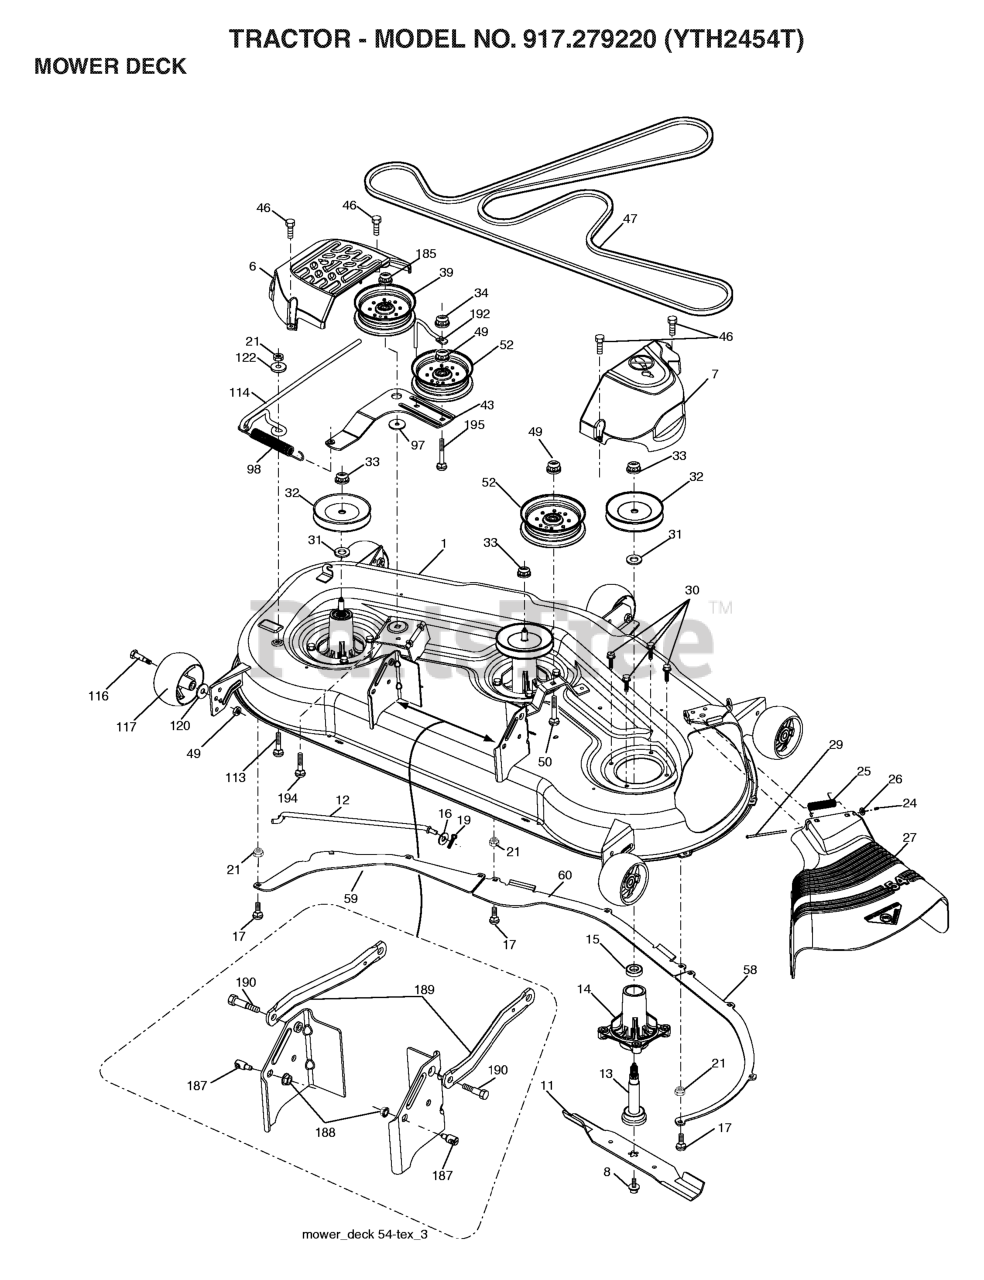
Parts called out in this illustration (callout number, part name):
1	DECK.WELDMENT.54"MS418
6	COVER.MANDREL.LH.54"20
7	COVER.MANDREL.RH.54.20
8	BOLT 7/16 ASM BLADE
11	BLADE.BAGGING.54"
12	ROD.ANTI.SWAY.48/54"TE
13	SHAFT ASM MANDREL
14	RP.HOUSING.MANDREL.4PT.
16	WASHER
17	BOLT
19	PIN.COTTER.5/16.BOW TI
21	LOCKNUT
24	CAP-SLEEVE LT
25	SPRING, TORSION
26	NUT PUSH M
27	DEFLECTOR
29	ROD.HINGE
30	SCREW, WASHER HEAD
31	WASHER.SPACER.MANDREL
32	MANDREL.PULLEY.38.BRIGHT.ZINC
33	NUT.FLANGE.LOCK.TOP
39	PULLEY.IDLER.MWR.STATI.LH
46	SCREW.1/4-20X5/8
47	RP.BELT.DRIVE.54."2006
49	NUT LOCK FLG 3/8-16 UNC
52	PULLEY.IDLER.2006
58	BAFFLE.RIGHT.54"
59	BAFFLE.LEFT.54"
60	BAFFLE CENTER 54" MOWER
98	SPRING, DECK DRIVE
114	ROD TENSION RELIEF
116	BOLT.SHOULDER.3/8-16X3-5/8.
117	RP WHEEL. GUAGE RALLY
120	WASHER
122	BUSHING.RELIEF.TENSION
185	NUT.LOCK.FLANGE.7/16
187	STUD.FASTNER.W/ANTI-ROTATE
188	NUT LOCK HEX FLANGE 5/16-18
189	ARM.SUSPENSION.MOWER
190	BOLT.SHOULDER
192	KEEPER.BELT.IDLER.54"T
194	BOLT.CARR.SQNK.7/16
